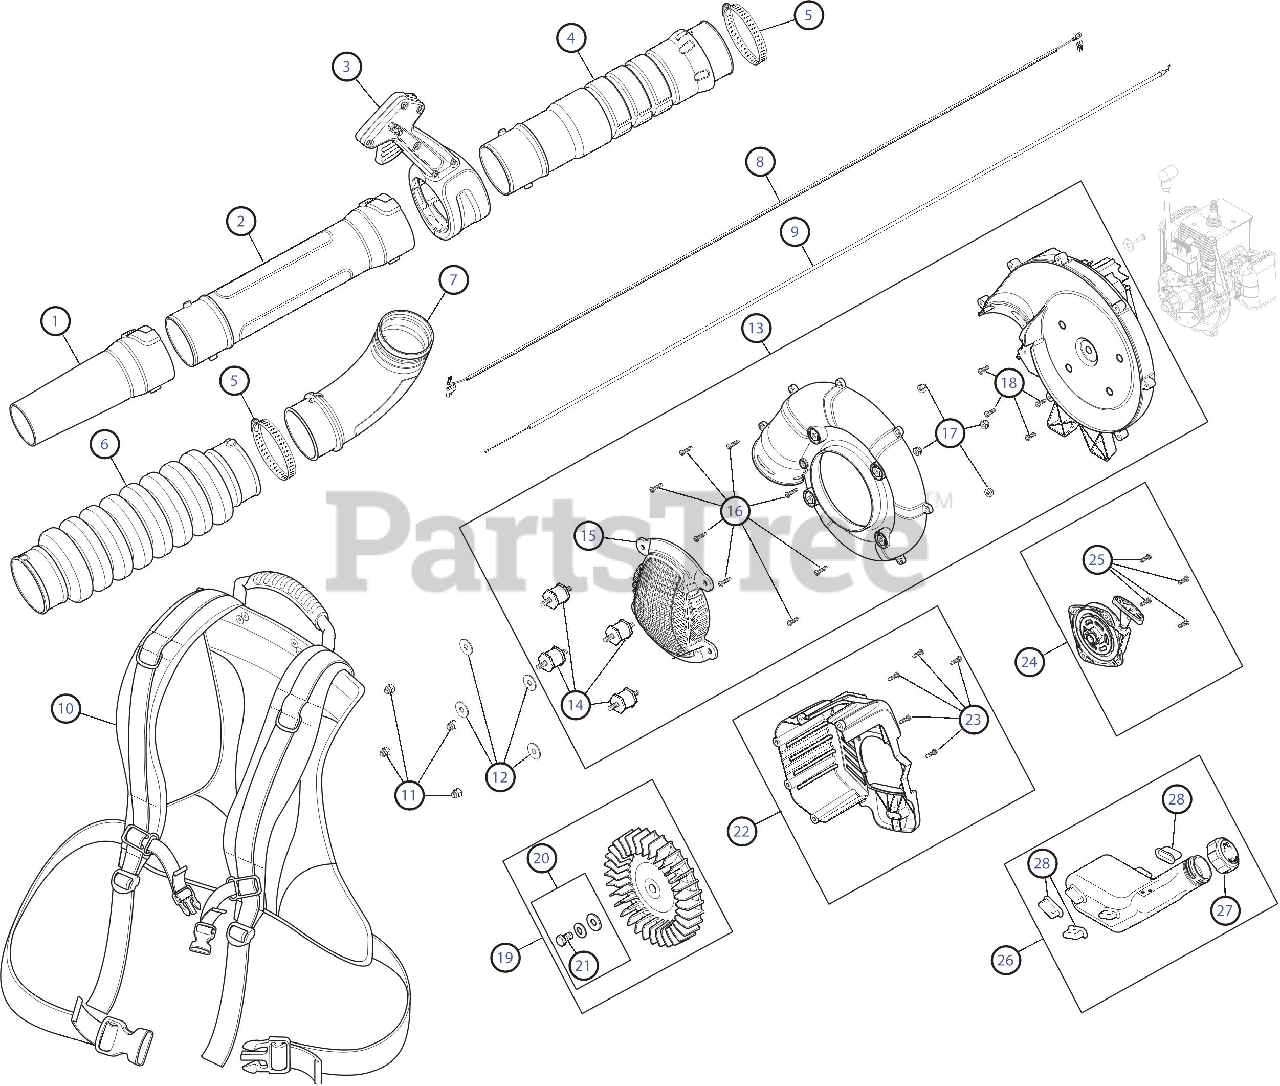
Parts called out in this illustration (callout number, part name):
2	Lower Blower Tube
3	Throttle Grip Assembly
4	Upper Blower Tube
9	Throttle Cable
11	Nut
12	Washer
13	Impeller Housing Assembly (Incl. 14 - 18)
14	Insulator Mount
15	Intake Cover
18	Screw
19	Impeller (Incl. 20 & 21)
20	Impeller Hardware (Incl. 21)
22	Housing Assembly (Incl. 23)
24	Starter Assembly (Incl. 25)
25	Screw
26	Fuel Tank Assembly (Incl. 27 & 28)
28	Fuel Tank Pads
